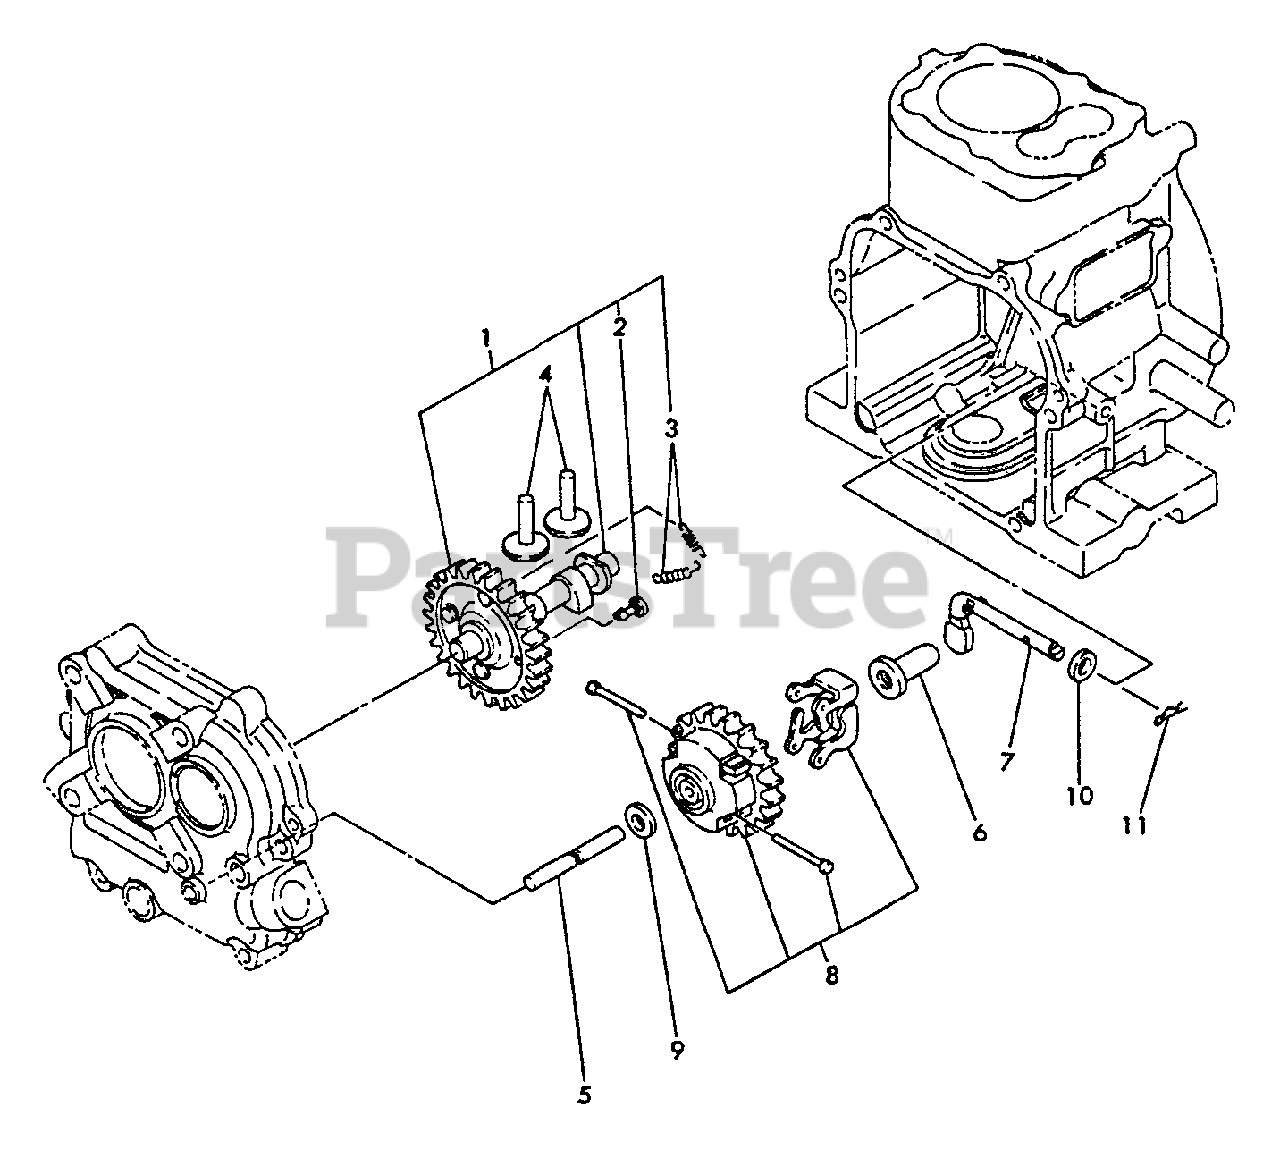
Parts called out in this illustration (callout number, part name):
1	CAMSHAFT ASSY
2	PIN, DECOMP.
3	SPRING
4	TAPPET
5	SHAFT, GOVERNOR
6	SPINDLE, GOVERNOR
7	SHAFT, GOV. LEVER
8	GOVERNOR GEAR ASSY
9	WASHER
10	WASHER - 6
11	PIN - 6 -- SNAP
